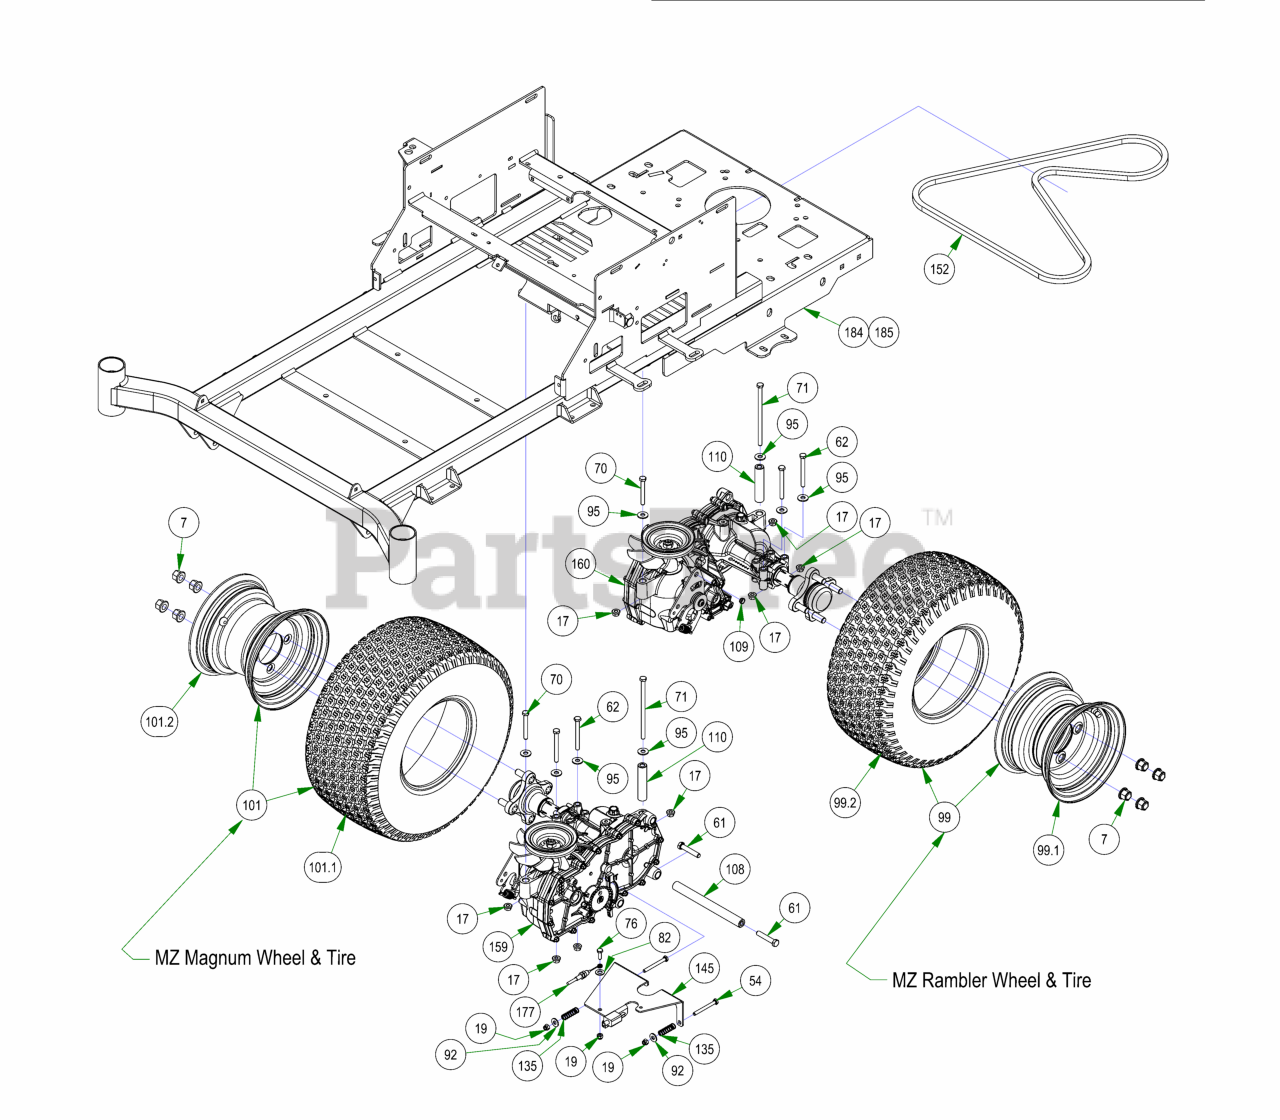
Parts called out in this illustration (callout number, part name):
7	Acorn Lug Nut
17	5/16-18 NYLON INSERT FLANGE LOCKNUT ZINC
19	1/4-20 NYLON INSERT LOCKNUT ZINC
54	1/4-20 X 2-1/2 HEX CAP SCREW (GR.2) ZINC
61	3/8-16 X 2 HEX CAP SCREW (GR.5) ZINC
62	5/16-18 X 3 HEX CAP SCREW (GR.5) ZINC
70	5/16-18 X 2-1/2 HEX CAP SCREW (GR.5) ZINC
71	5/16-18 X 6 HEX CAP SCREW (GR.5) ZINC
76	1/4-20 X 3/4 HEX CAP SCREW (GR.5) ZINC
82	.390 ID X .750 OD X .062 THK FLAT WASHER NYLON
92	1/4 USS FLAT WASHER (3/4 OD) ZINC
95	5/16 USS FLAT WASHER (7/8 OD) ZINC
99	18x8.50-8 x/*" Tire & Wheel (Black)
99.1	Rim for 022-2050-22
99.2	Tire for 022-2050-22
101	18x9.50-8 Tire and Wheel - Black Wheel
101.1	18x9.50-8 Rear Tire Only 48 MZ
101.2	Black Rear Wheel 48in MZ
108	2017 Transaxle Spacer-MZ
109	Drive Arm Transaxle Spacer
110	2017 Transaxle Spacer
135	Brake Spring
145	2017 MZ/Magnum Brake Plate Assembly
159	2017 EZT -Right -MZ Models
160	2017 EZT -Left -MZ Models
177	MZ Brake Cable
184	2023 MZ 42-48 Frame - Painted
185	2023 MZ-Avenger 54-60 Frame - Painted
